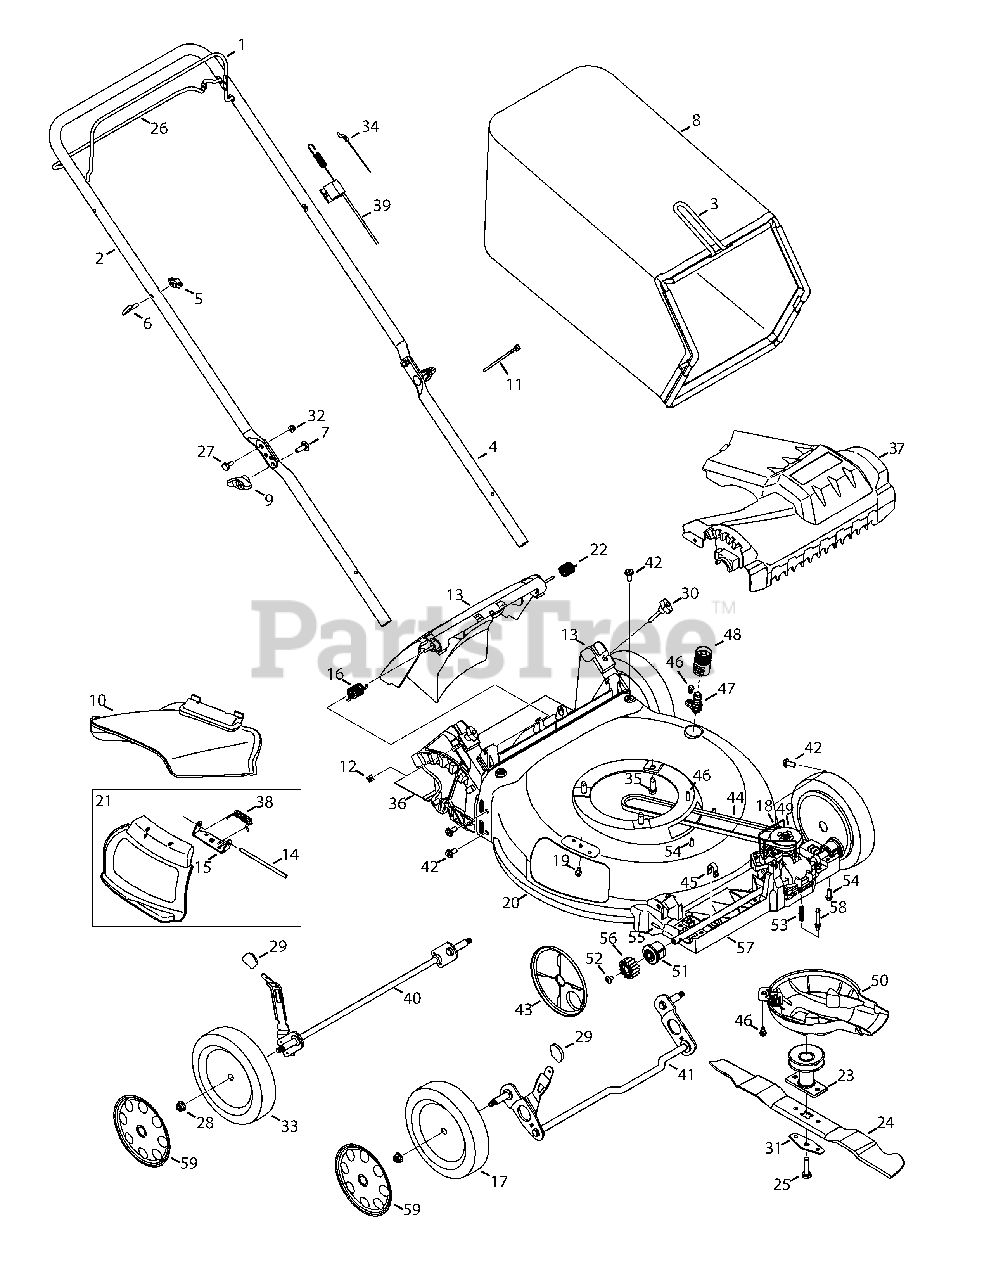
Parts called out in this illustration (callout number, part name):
1	Blade Control
2	Upper Handle
3	Grass Catcher Frame
4	Lower Handle
6	Rope Guide
7	Carriage Screw, 5/16-18
8	Grass Bag
10	Side Chute
11	Cable Tie
12	Nut, Sq., 1/4-20
13	Rear Discharge Door Assembly
15	Chute Deflector Bracket
16	Torsion Spring - RH
17	Front Wheel
18	Transmission Wire
19	Screw, 1/4-20 x .500
20	Deck , 21"
21	Hinged Mulch Plug Assembly
22	Torsion Spring - LH
23	Blade Adapter Assembly
24	Mulching Blade
25	Screw , 3/8-24 x 1.50
26	Drive Control
27	Sldr. Screw, .375 x .126 x 1/4-20
28	Flange Lock Nut, 3/8-16
29	Adjustment Lever Knob
30	Wing Nut
31	Blade Bell Support
32	Nut, Flange Lock, 1/4-20
33	Rear Wheel
34	Control Cable
35	TT Sems Screw, 3/8-16 x 1.0
36	Trail Shield
37	Front Cover
38	Torsion Spring
39	Drive Cable
40	Rear Axle Assembly
41	Front Axle Assembly
42	Screw, 5/16-14 x .750
43	Wheel Dust Cover
45	Front Axle Clip
46	Scr., Shldr., 1/4-20 x .50
47	Water Nozzle
48	Water Nozzle Adapter
49	Transmission Assembly
50	Engine Baffle
51	Bearing Assembly
52	Screw, 1/4-20 x .390
53	Compression Spring
54	Screw, 1/4-15 x .750
56	Spur Gear, 14T - RH
56	Spur Gear, 14T - LH
57	Lower Tray
58	Spring Body
59	Hubcap, 8"
